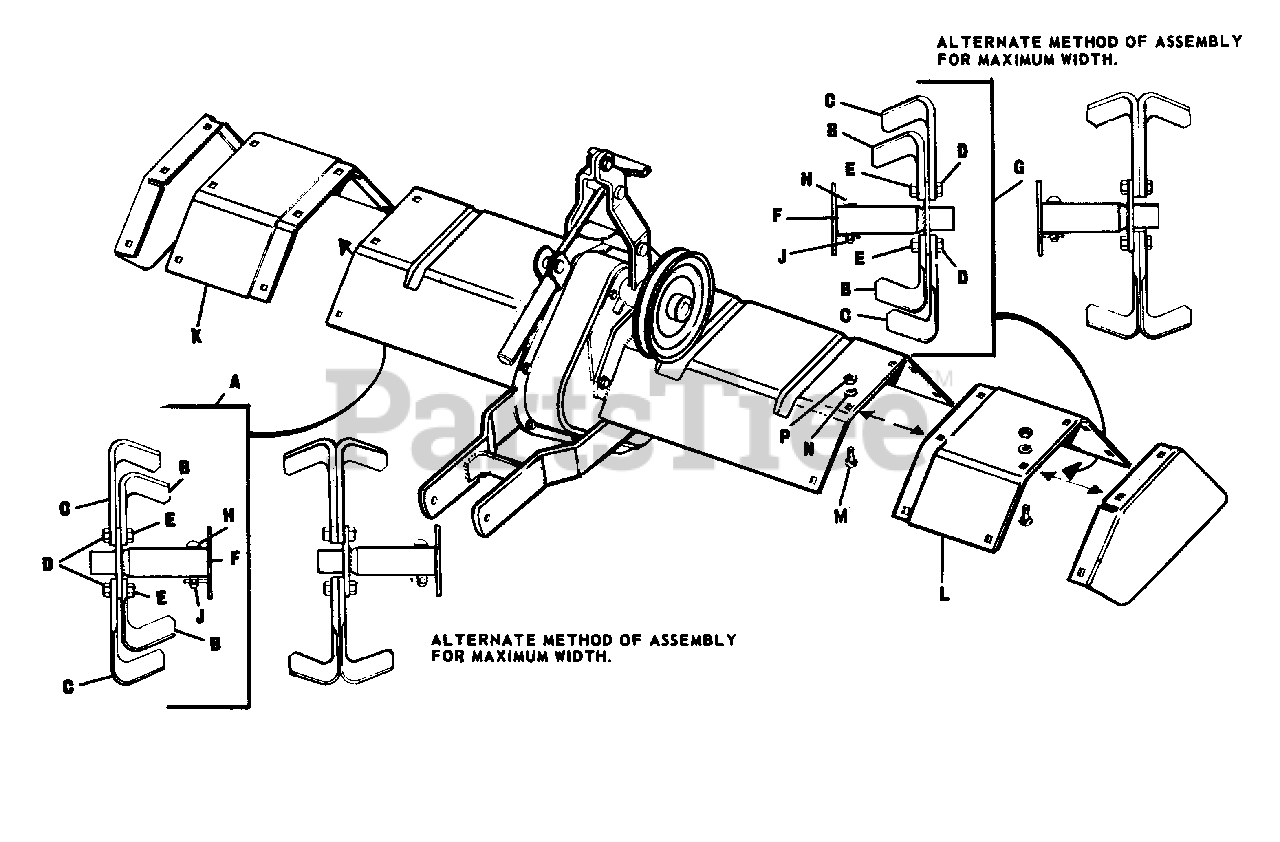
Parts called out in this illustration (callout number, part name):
A	Blade Assembly, L.H.
B	Blade, L.H. Tine
C	Blade, R.H. Tine
D	Hex. Cap Screw, 7/16"-20 x 1-1/4
E	Full Lock Nut, 7/16"-20
F	Plate Assembly, Tine Extension
G	Blade Assembly, R.H.
H	Tine Shaft Pin
J	Spring Clip
K	Deflector Extention, R.H.
L	Deflector Extention, L.H.
M	Carriage Bolt, 5/16"-18 x 1/2"
N	Lock Washer, 5/16"
P	Full Hex. Nut, 5/16"-18
